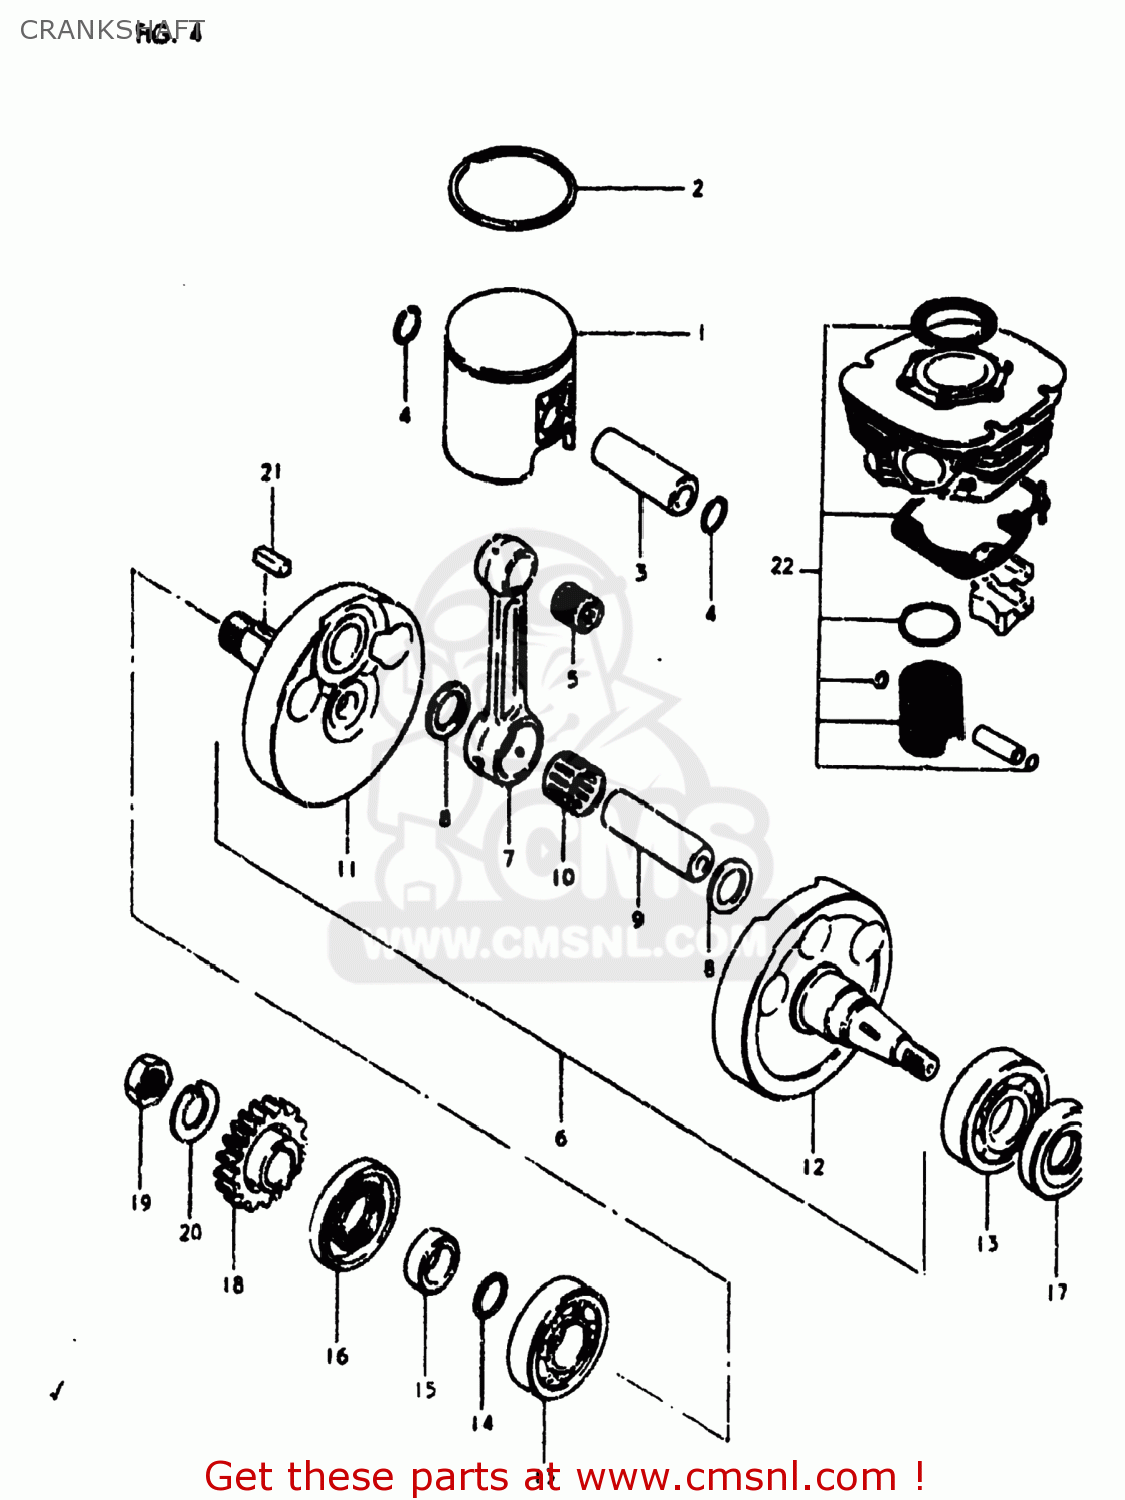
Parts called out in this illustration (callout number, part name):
1	PISTON
2	RING,PISTON
3	PIN,PISTON (18MM)
4	CIRCLIP
5	BEARING(18X22X22)
6	CRANKSHAFT ASSEMBLY
7	ROD,CONNECTING
8	WASHER(24X29X2)
9	PIN,CRANK
10	BEARING
11	CRANKSHAFT
12	CRANKSHAFT,LEFT
13	BEARING
14	O RING(D:2.4,ID:21.8)
15	SPACER (22X37X12.5)
16	SEAL,OIL(37X62X9)
17	SEAL,OIL(24X50X9)
18	GEAR,PRIMARY DRIVE
19	NUT
20	WASHER
21	KEY
22	PISTON SET
